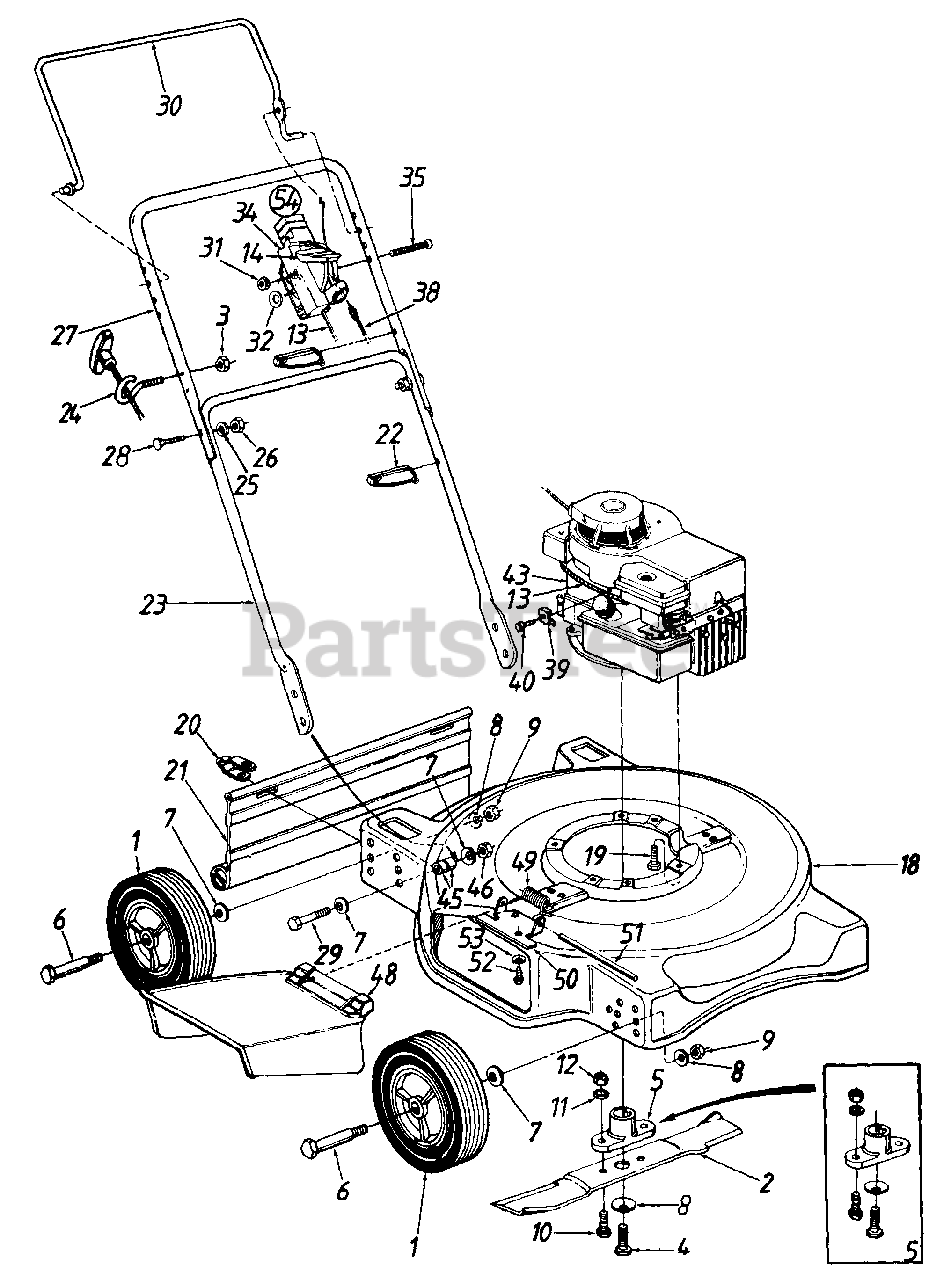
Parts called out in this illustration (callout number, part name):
1	Wheel Ass'y. Complete
2	20" Blade
3	Hex L-Nut 1/4-20 Thd.
4	Hex Bolt 3/8-24 x 1.5" Lg.
5	Blade Adapter Kit (Keyed)
7	Bell-Wash. .380" I.D. x .88"
8	Bell-Wash. .39" I.D. x 1.13"
9	Hex Nut 3/8-16 Thd.
10	Hex Bolt 3/8-24 x 1" Lg.
11	L-Wash. 3/8" I.D.
12	Hex Nut 3/8-24 Thd.
13	Throttle Wire 51" Lg.
14	Throttle Wire Lever
18	20" Deck Ass'y.
19	Hex Wash. Hd. Scr. 3/8-16 x 1" Lg.
20	Hinge Clip
21	Rear Flap 16.75" Lg.
22	Cable Tie
23	Lower Handle
25	L-Wash. 5/16" I.D.
26	Hex Nut 5/16-18 Thd.
29	Hex Bolt 3/8-24 x 1.5" Lg.
31	Hex L-Nut 1/4-20 Thd.
32	Spr. Wash. .66" I.D.
34	Throttle Body
35	Oval C-Sunk Scr.
38	Control Cable - 39"
39	Casing Clamp
40	Hex Wash. Hd. Scr. #10-32 x .62" Lg.
43	Engine
45	Spacer .391" I.D. x .375" Lg.
46	Hex L-Nut 3/8-24 Thd.
48	Chute Deflector Ass'y.
49	Torsion Spring
50	Adapter Plate
51	Hinge Pin
52	Hex Self-Tap Scr. 1/4-20 x .5"
53	Bell-Wash. 1/4" I.D.
54	Throttle Box Complete
